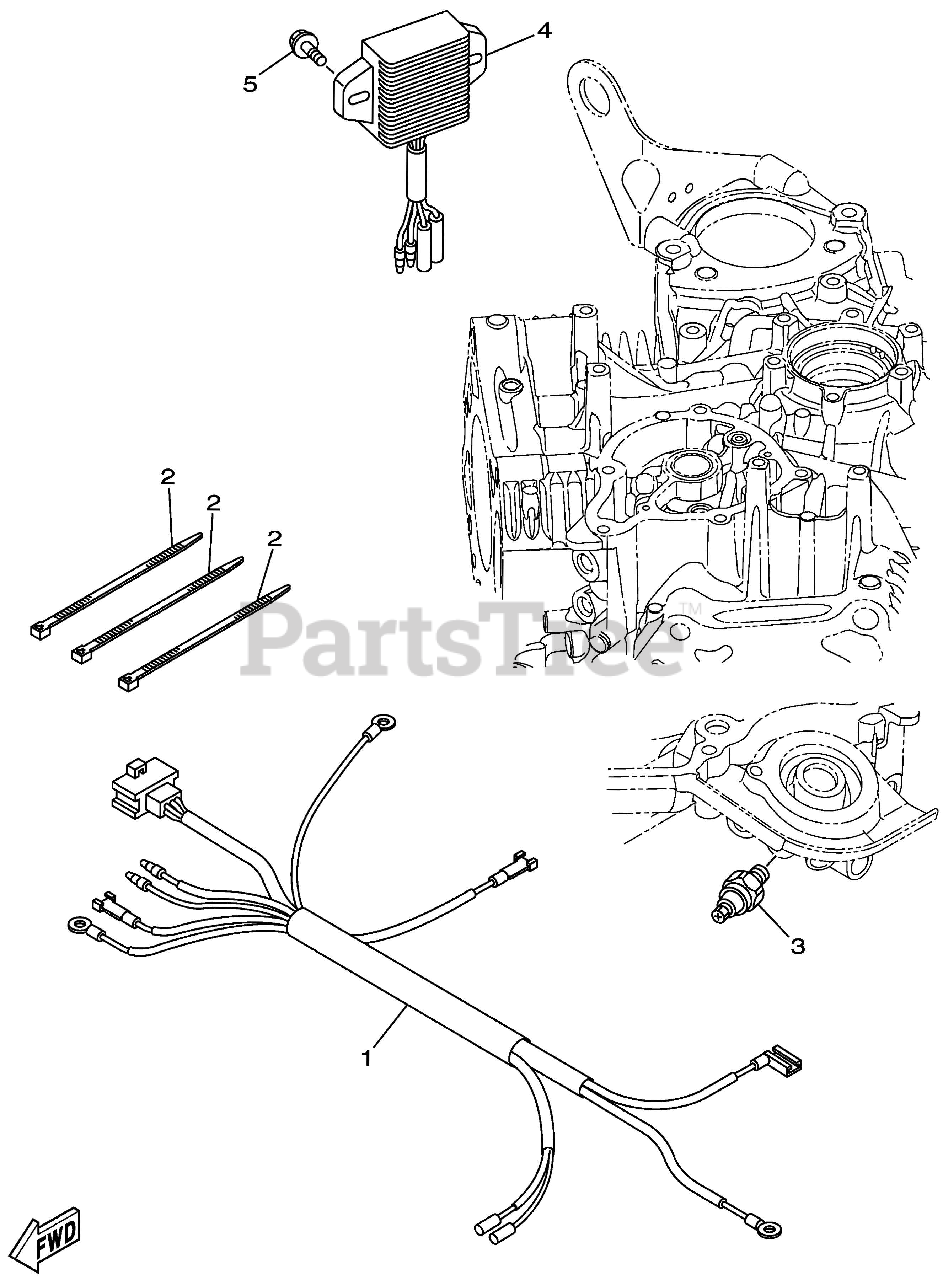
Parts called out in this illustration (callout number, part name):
1	WIRE, LEAD
3	OIL PRESSURE SWITCH ASSY
4	RECTIFIER & REGULATOR ASSY
5	BOLT, FLANGE
